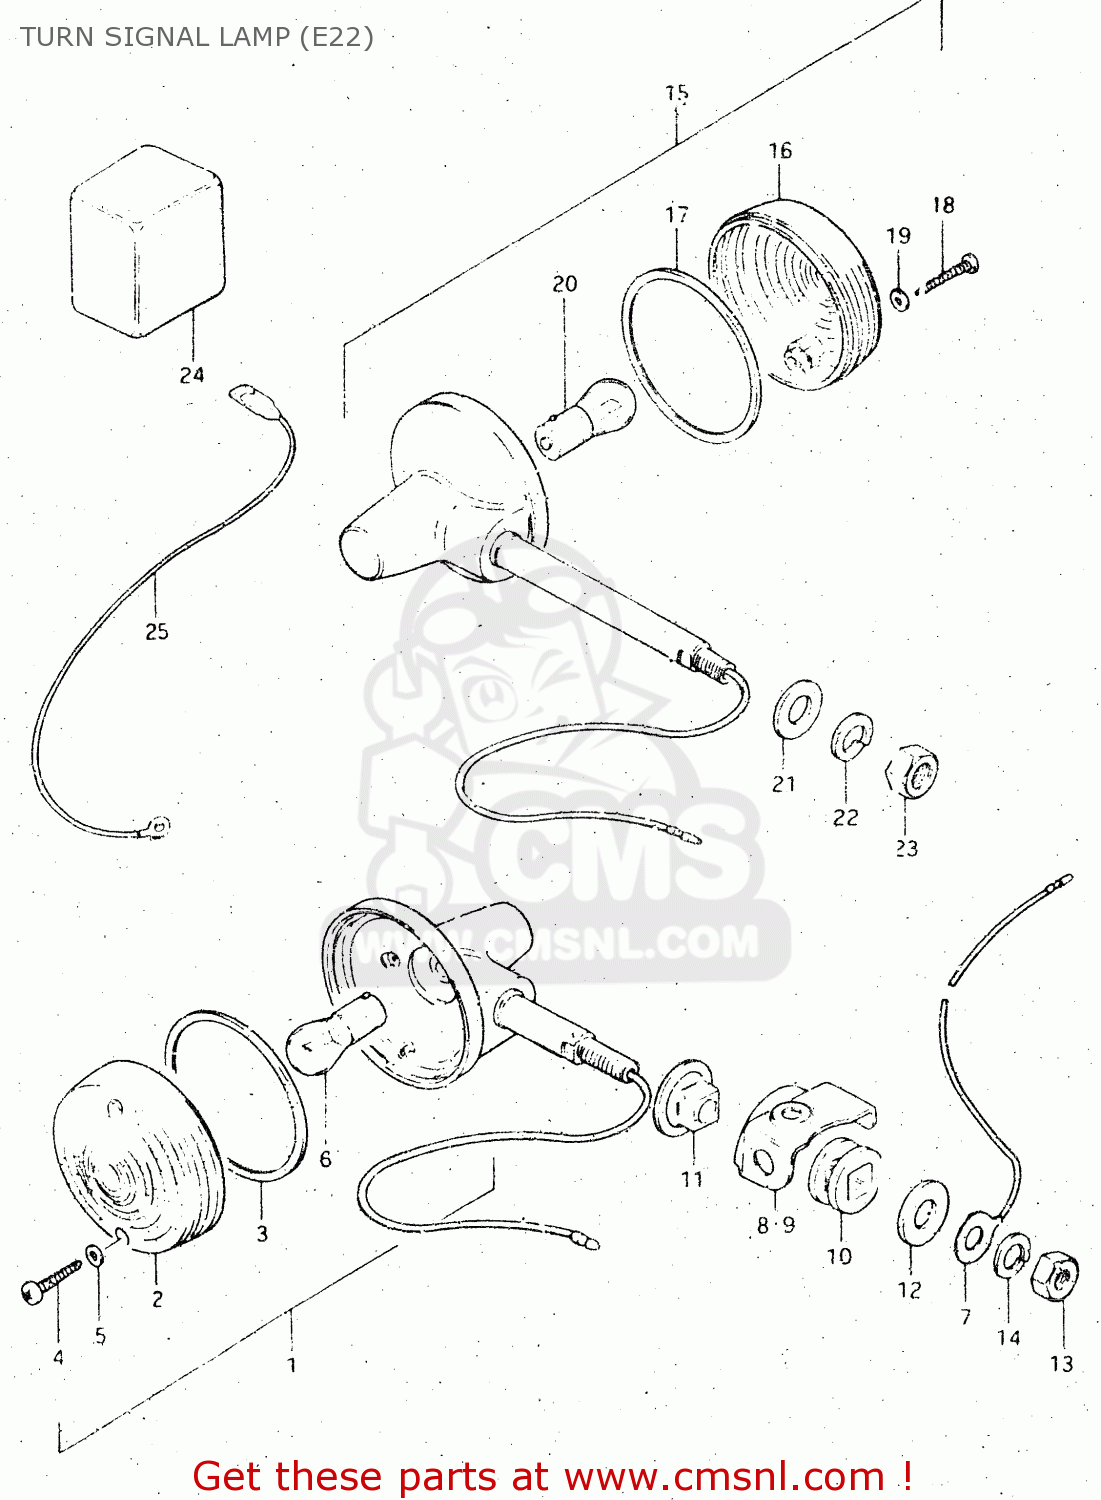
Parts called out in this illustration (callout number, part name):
1	LAMP, FRONT TURN SIGNAL
2	LENS
3	GASKET (NAS)
4	SCREW
5	GASKET (NAS)
6	BULB (6V,21W)
7	LEAD WIRE,EARTH
8	BRACKET, FRONT RH
9	BRACKET, FRONT LH
10	CUSHION
11	SPACER
12	WASHER (10.5X30X2.3)
13	NUT
14	LOCK WASHER
15	LAMP, REAR TURN SIGNAL
16	LENS,TURN SIGN
17	GASKET (NAS)
18	SCREW
19	GASKET (NAS)
20	BULB (6V,21W)
21	WASHER
22	LOCK WASHER
23	NUT
24	RELAY ASSY, TURN SIGNAL
25	LEAD WIRE, RELAY EARTH
